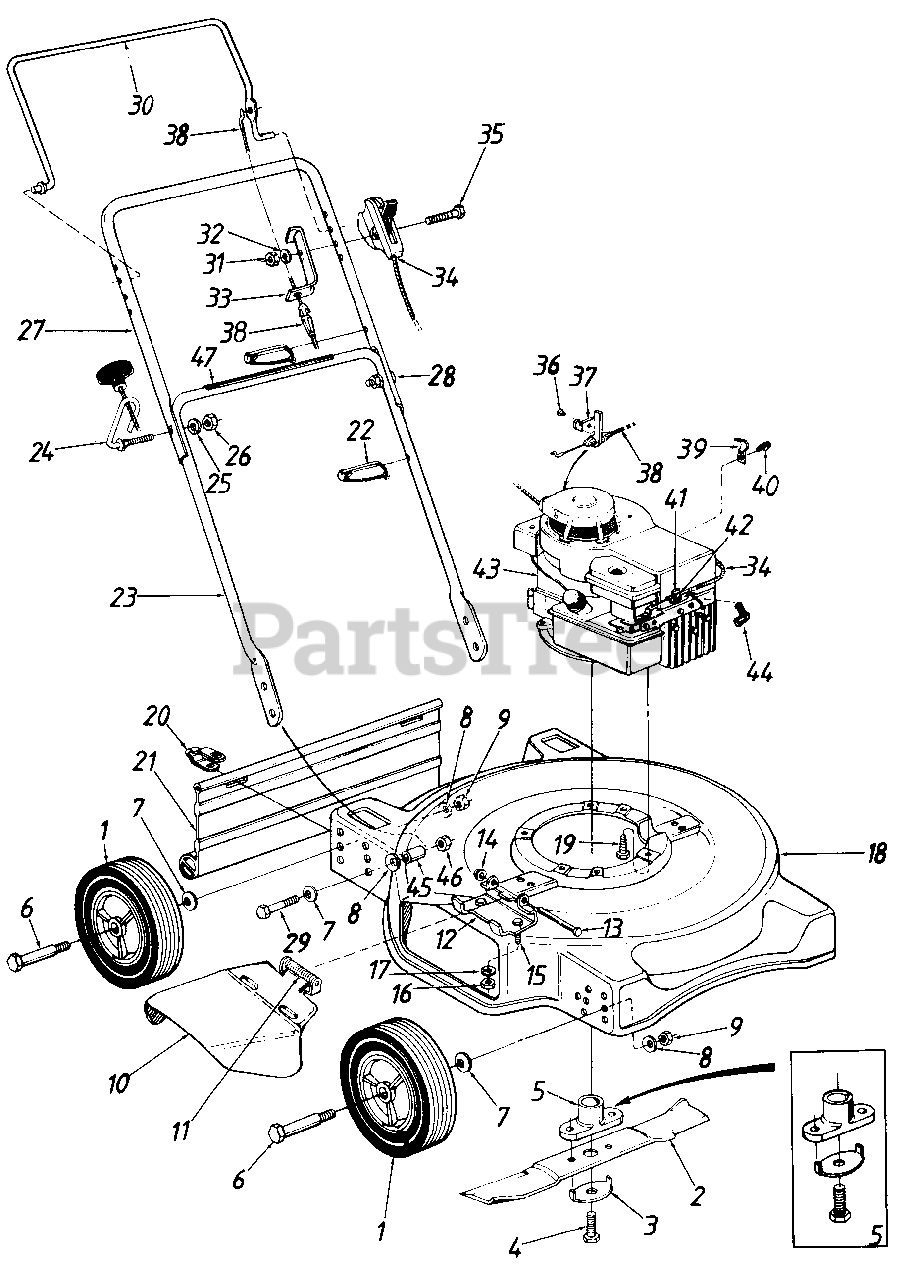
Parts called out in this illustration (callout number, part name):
1	Wheel Ass'y. Complete
2	20" Blade
3	Blade Bell-Wash. .45" I.D. x 2.38"
4	Hex Bolt 3/8-24 x 1.5" Lg.
5	Blade AdaDter Kit
6	Front Axle Bolt
7	Bell-Wash. .380" I.D. x .88" O.D.
8	Bell-Wash. .39" I.D. x 1.13" O.D.
9	Hex Nut 3/8-16 Thd.
10	Chute Deflector Ass'y.
11	Torsion Spring
12	Adapter Plate
14	Speed Nut 1/4" Rod
15	Hex Bolt 1/4-20 x .5" Lg.
16	Hex Nut 1/4-20 Thd.
17	L-Wash. 1/4" I.D.
18	20" Deck Ass'y.
19	Hex Wash. Hd. Scr. 3/8-16 x 1" Lg.
20	Hinge Clip
21	Rear Flap 16.75" Lg.
22	Cable Tie
23	Lower Handle
24	Rope Guide Bolt
25	L-Wash. 5/16" I.D.
26	Hex Nut 5/16-18 Thd.
27	Upper Handle
28	Curved Carriage Bolt 5/16-18 x 1.38" Lg.
29	Hex Bolt 3/8-24 x 1.5" Lg. Grade 5
30	Control Handle
31	Hex Nut 1/4-28 Thd.
32	Spr. Wash. .265" I.D. x .562" Lg.
33	Cable Mounting Bracket
34	Throttle Control Ass'y. Comp.
35	Hex Bolt 1/4-28 x 1.75" Lg.
36	Pop Rivet .156" Dia. x .316
37	Cable Bracket
38	Control Cable
39	Casing Clamp
40	Hex B-Tap Scr. #10 x .38" Lg.
41	Casing Clamp
42	Hex Wash. Hd. AB-Tap Scr. #8 x .50" Lg.
43	Engine
44	Spark Plug Boot
45	Spacer .381" I.D. x .56" O.D. x . 75 " Lg.
46	Hex Lock Nut 3/8-24 Thd.
47	Instruction Label-Handle
